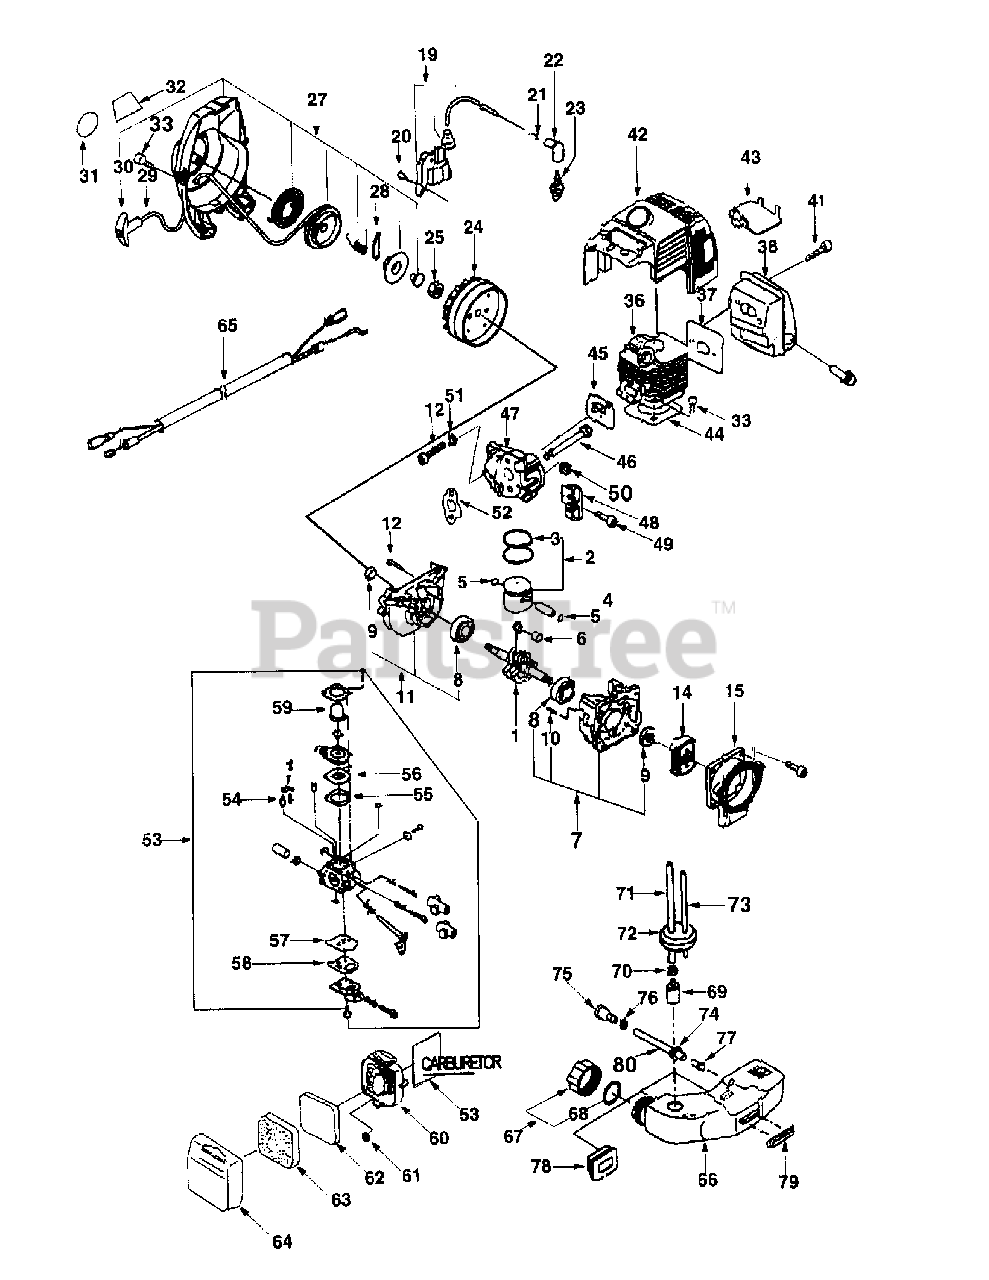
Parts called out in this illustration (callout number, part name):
1	Crankshaft
2	Piston Assembly
3	Ring, Piston
4	Pin, Piston
5	Clip, Piston Pin
6	Needle Bearing
7	Crankcase Assembly
8	Ball Bearing
9	Oil Seal
10	Dowel Pin
11	Crankcase Assembly
12	Bolt. M5 x 25
14	Clutch Assembly
19	Coil Assembly, Ignition
20	Bolt. M4 x 20
22	Cap, Plug
23	Spark, Plug
24	Flywheel, Magneto
27	Housing Assembly, Blower
29	Rope, Starter
30	Knob, Starter
31	Name Plate
32	Caution Plate
33	Bolt. M5 x 16
36	Cylinder
37	Gasket, Muffler
39	Arrester
41	Bolt. M5 x 48
42	Cowling, Cylinder
43	Baffle Plate
45	Gasket, Insulator
46	Bolt. M5 x 56
47	Insulator
48	Adjuster
49	Bolt. M5 x 12
51	Washer
52	Gasket, Carburetor
53	Carburetor Assembly
54	Valve, Float
56	Diaphragm, Metering
57	Diaphragm, Pump
60	Case, Air Silencer
62	Element (B), Air Filter
63	Element (A), Air Filter
64	Case, Cap
65	Wire Compl, Throttle
66	Tank, Fuel
67	Cap Assembly, Fuel Tank
69	Filter, Fuel
71	Hose
73	Hose
75	Valve Assembly, Reversing
77	Connector
79	Rubber
81	Gasket Kit
83	Spring, Spiral
